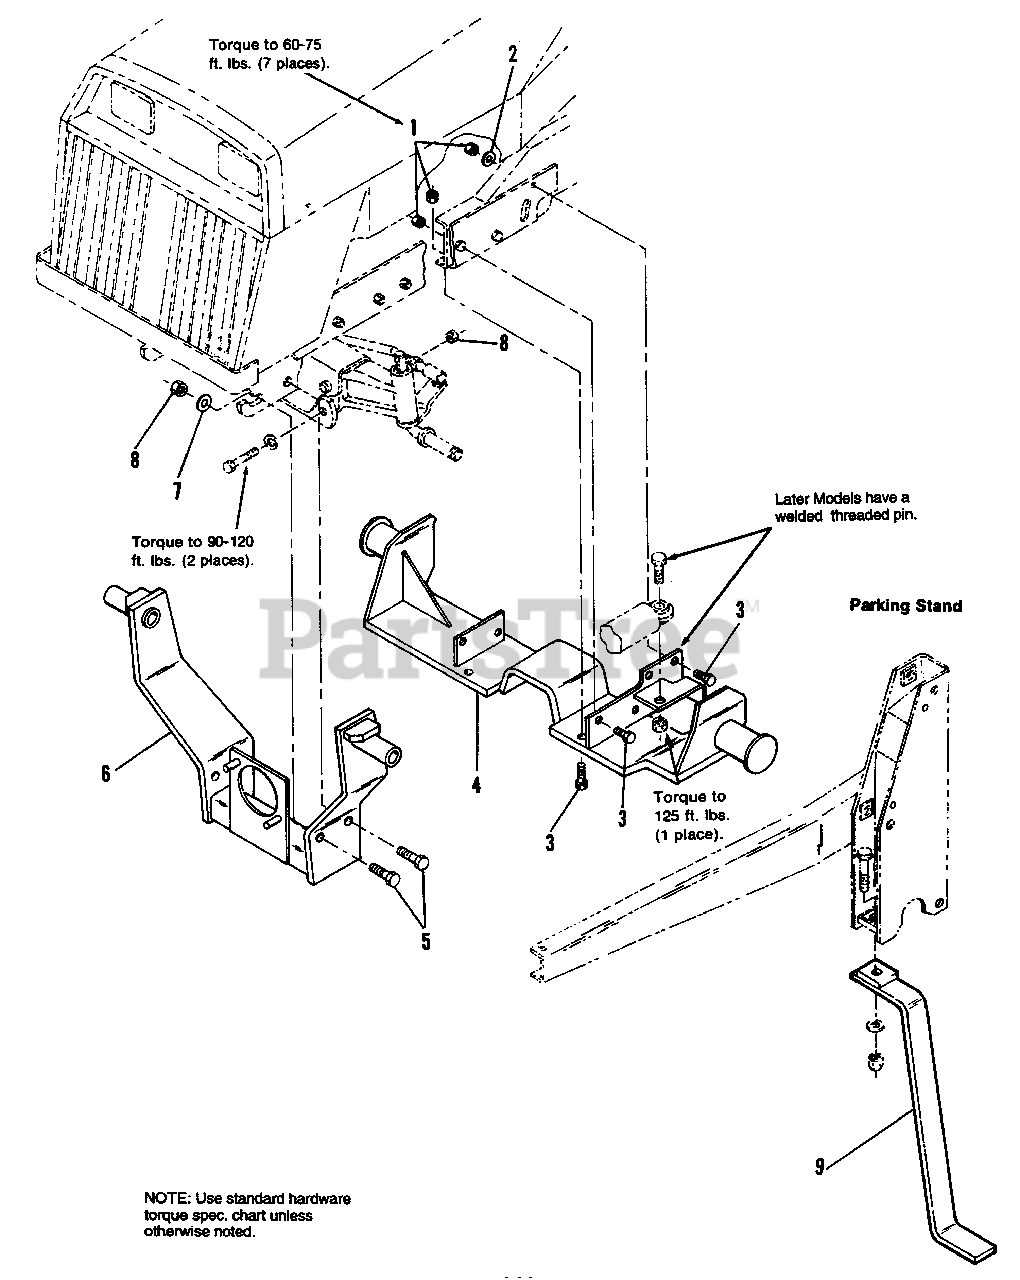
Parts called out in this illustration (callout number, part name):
1	NUT, Centerlock, 1/2-13
2	WASHER, Flat, 1/2 x1, 12 Ga.
3	CAPSCREW 1/2-13 x 1-1/2
4	BRACKET, Mid Mounting
5	CAPSCREW 5/8-11 x 2
6	BRACKET, Front Mounting
7	WASHER, Flat, 5/8
9	STAND, Parking (Loader)
